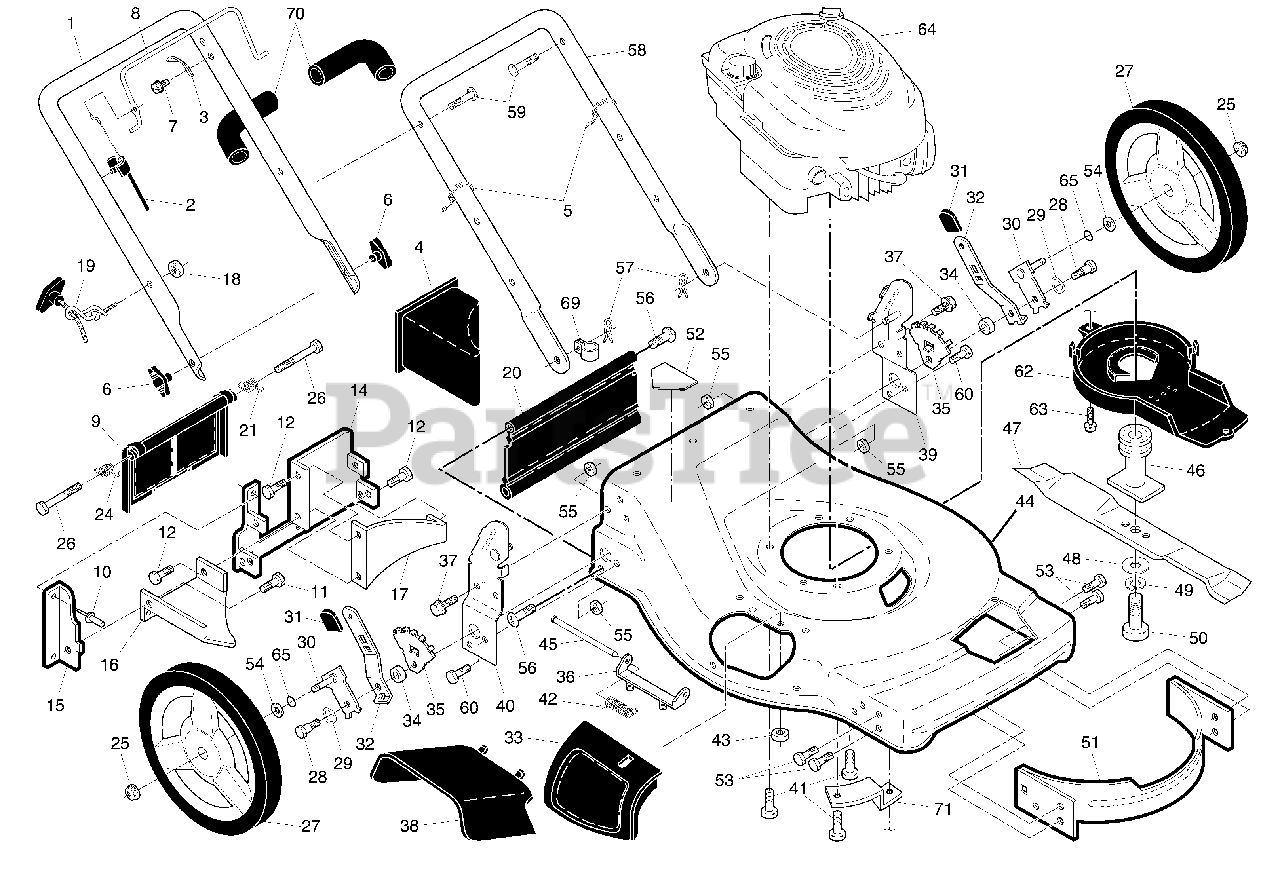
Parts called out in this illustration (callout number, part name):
1	Upper Handle
2	Engine Zone Control Cable
3	Bracket, Upstop
4	Mulcher Plug
5	Wire Tie
6	Handle Knob
8	Control Bar
9	Rear Door Assembly
11	Screw, Self-Tapping #10-24 x 5/8
12	Screw, Hex Hex Head, Sems 1/4-20 x 1/2
14	Back Plate
15	Side Baffle
16	Discharge Baffle
17	Rear Baffle
18	Keps Locknut 1/4-20
19	Rope Guide
20	Rear Skirt
21	Spring, Rear Door, LH
24	Spring, Rear Door, RH
25	Nut, Hex, Flanged
26	Bolt, Rear Door
27	Wheel, Rear
28	Bolt, Shoulder 3/8-16 x 1
29	Washer, Curved, Cylindrical
30	Axle Arm Assembly
31	Selector Knob
32	Selector Spring
33	Mulcher Door
35	Wheel Adjusting Bracket
36	Hinge Bracket Assembly
37	Screw, Sems, Thread Cutting 5/16-18 x 3/4
38	Discharge Deflector
39	Handle Bracket Assembly, LH
40	Handle Bracket Assembly, RH
41	Bolt, Engine
42	Spring, Torsion
43	Nut, Hex, Nylock
44	Kit, Lawn Mower Housing
45	Rod, Hinge
46	Blade Adapter / Pulley
47	Blade, 22"
48	Washer, Hardened
49	Washer, Helical
50	Screw, Machine, Hex Head 3/8
51	Front Baffle
52	Danger Decal
55	Locknut, Hex 3/8-16
56	Screw, Hinge 1/4-20 x 1-1/4
57	Hairpin Cotter
58	Lower Handle
59	Handle Bolt
61	Nut
62	Debris Shield
63	Screw, Debris Shield
69	Clip, Cable
71	Mounting Bracket, Debris Shield
